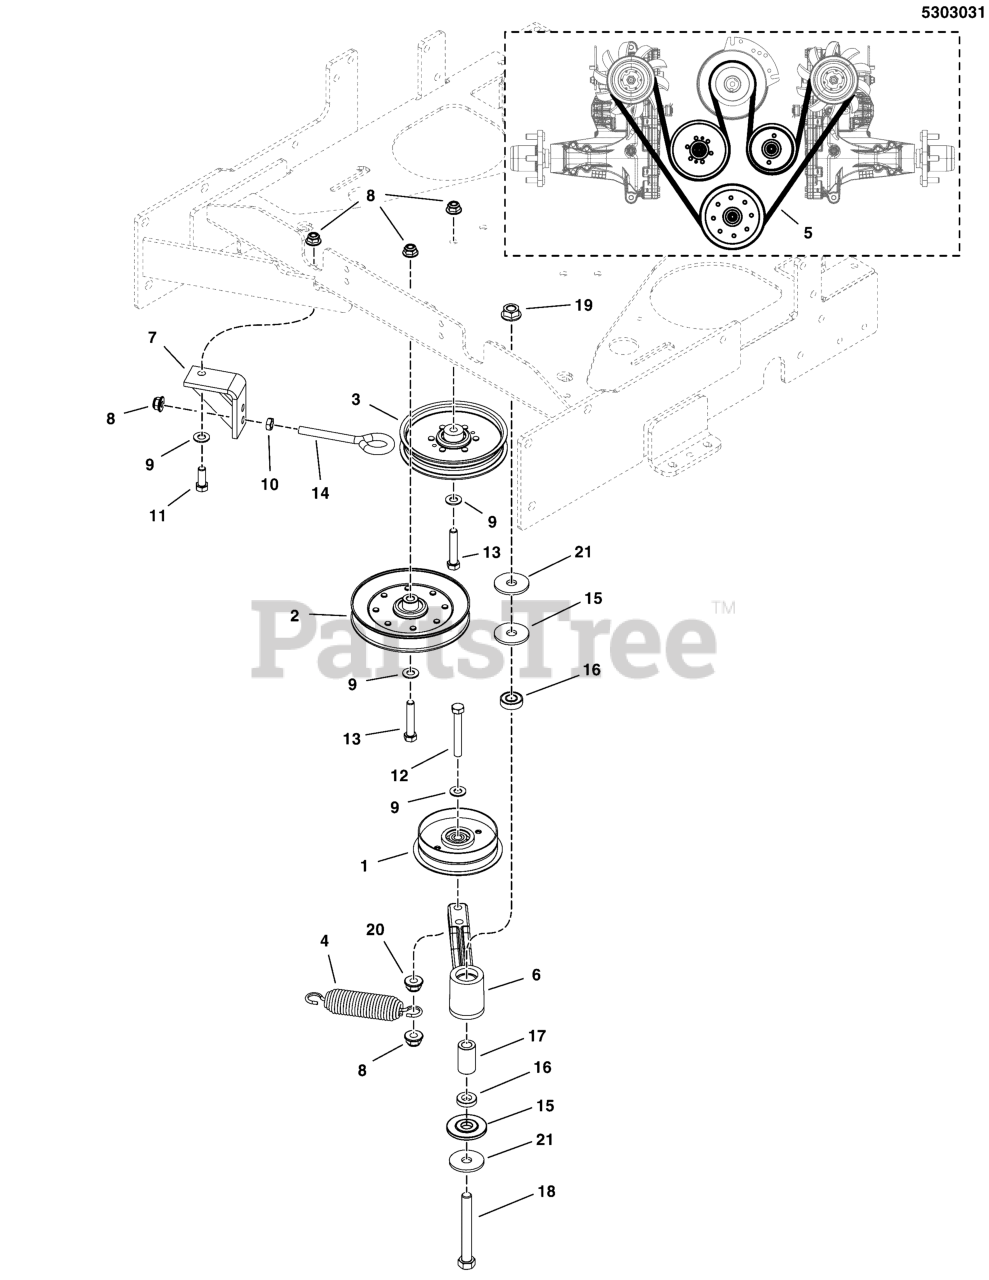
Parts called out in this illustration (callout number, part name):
1	PULLEY, IDLER, SINGLE FLANGE, 4" OD
2	PULLEY-IDLER-V, 5.83OB, .38ID, .94W, STL
3	PULLEY-IDLER, 5.00OD, .385ID, .75W, STL
4	SPRING-EXT, 1.25 ODX5.70LGX.142WR, BLK
5	BELT, A-SEC, 100.00EL, ARAMID, WRPD
6	ASSM, IDLER ARM, PUMP DRIVE, 1/2ID, CAST
7	WELD, ANCHOR EYEBOLT
8	NUT, 3/8-16 HEX NYLOCK FLANGE
9	WASHER, 3/8 SAE
10	NUT, 3/8-16 HEX JAM
11	BOLT, 3/8-16 X 1-1/4" GD5 CZ
12	BOLT, 3/8-16 X 2-1/2" GD5 CZ
13	BOLT, 3/8-16 X 2, GD5, CZ
14	EYE BOLT, 3/8-16 X 5, 2.88THRD, 1EYE, CZ
15	SPACER, IDLER ARM, 1/2"
16	BEARING, BALL, AXLE
17	SPACER, .52 X .84 X 1.53, PM
18	BOLT, 1/2-13 X 4" GD5 CZ
19	NUT, Hex Flange, Nylock, 1/2-13
20	NUT, 3/8-16 HEX SERRATED FLANGE
21	WASHER, .52 X 1.75 X .14, CZ
